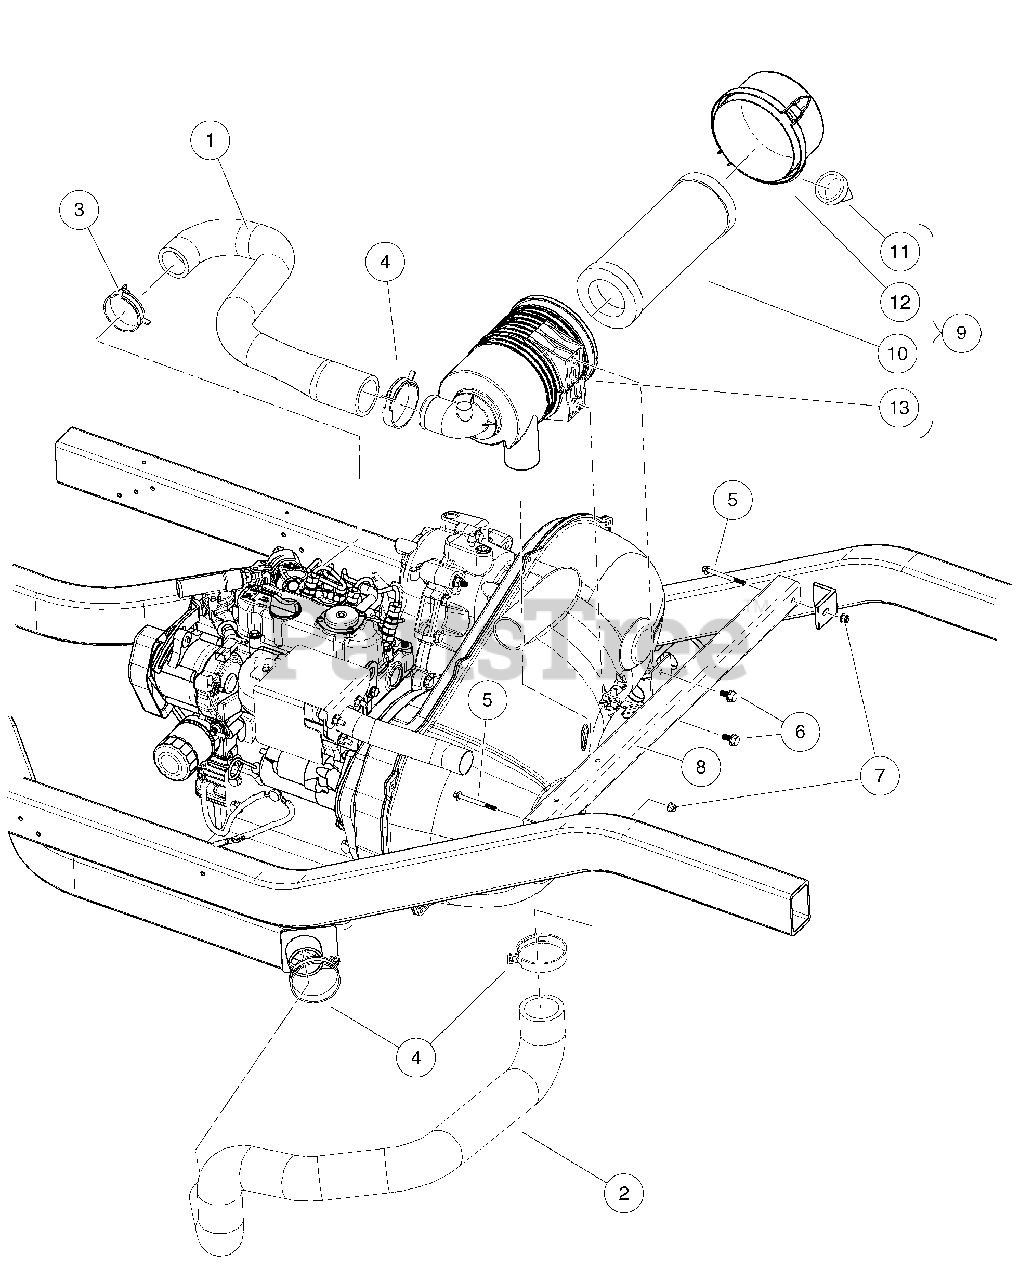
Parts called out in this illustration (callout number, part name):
1	Hose, Intake, D722
2	Hose, Intake, Primary
3	Clamp, Hose, Ctb 55mm
4	Clamp, Hose, Ctb 64mm
5	Bolt, M 6 X 1.0 X 65 Hex, Flange, Head, Black
6	Bolt Flanged Head, M8 X1.25x 16 with Loctite
7	Nut Flg, M6 X 1.0 Nylon
8	Weldment, Support, Air Cleaner
9	Filter, Air, Canister, W/labe
10	Element, Filter, Air, 5 In
11	Valve, Evacuator, Filter Air
12	Cap, Latch Lock, Filter, Air
13	Body, Canister, Filter, Air
